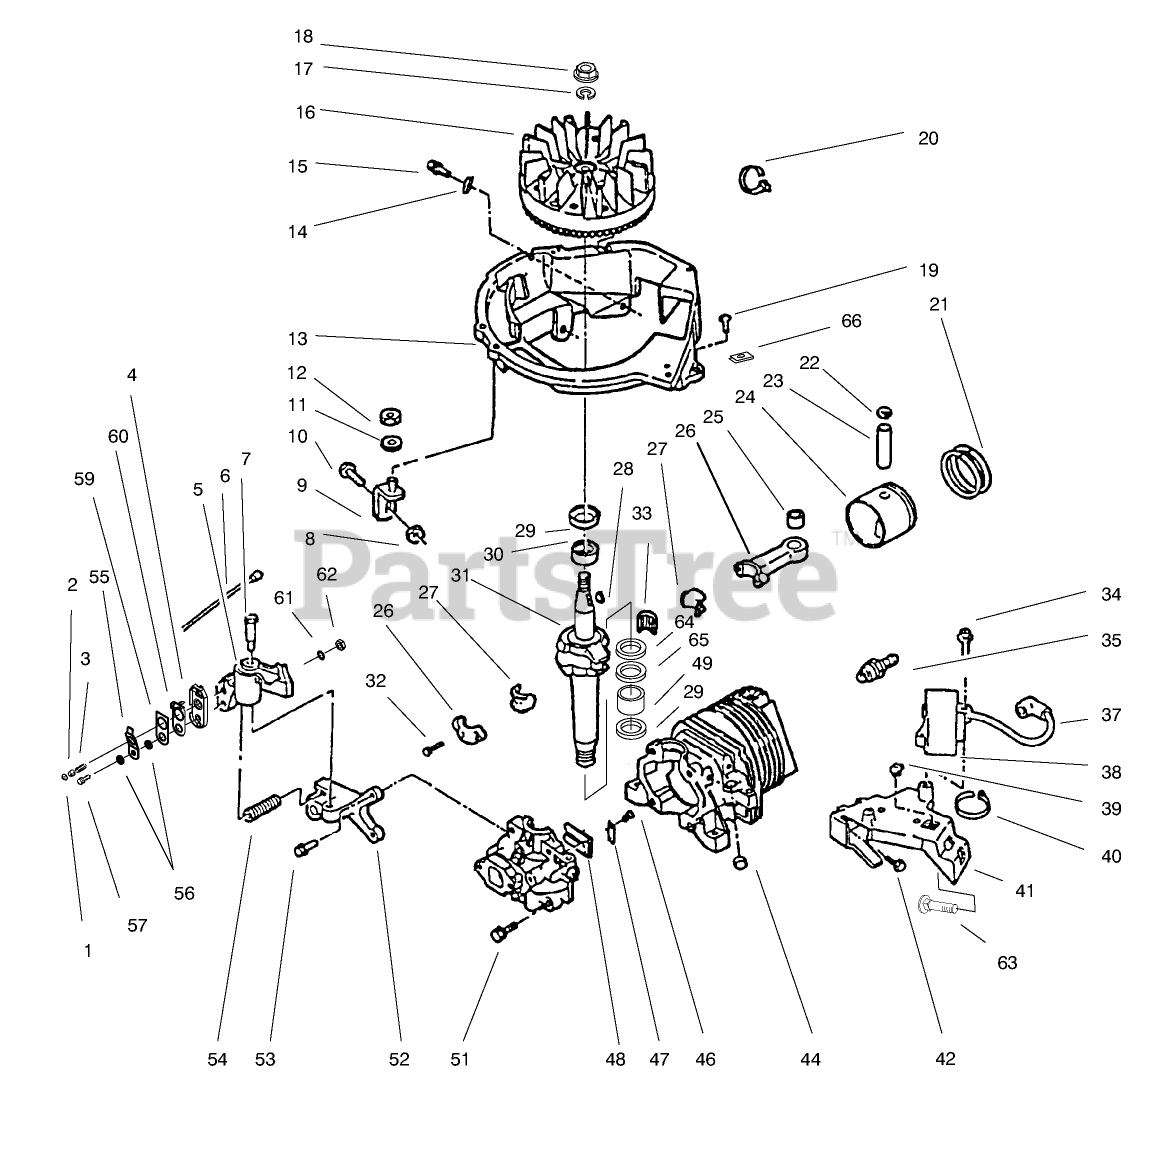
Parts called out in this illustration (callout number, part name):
1	RETAINER S
2	ACTUATOR-LEVER, BRAKE
3	SPRING
4	CASE - SWITCH EF
5	BRAKE AY FE
6	WIRE LEAD AY F
7	SCREW-SHOULDER
8	NUT-LOCK F
9	BRACE AY F
10	BOLT F
11	WASHER
12	LOCKNUT E
13	BASE SHROUD F
14	"J" CLIP F
15	SCREW F
16	FLYWHEEL ASSY F
17	WASHER-LOCK
19	SCREW F
20	STRAP-TIE
21	F-RING SET
22	RING-RETAINING
23	PIN-WRIST VF
24	Set-Piston & Ring (Incl. Ref.# 21-23)
25	BEARING XEV
26	Assembly-Conn. Rod (Incl. Ref. #25, 27, 32, & 33)
27	LINER ASM
29	SEAL-OIL
30	BEARING V
31	CRANKSHAFT V
32	SCREW-HSH
33	Roller Strip
34	SCREW F
35	SPARK PLUG
37	HT LEAD&COVER XEV
38	C. D. Ignition Module (Incl. Ref. #37)
39	NUT-CLIP
40	TIE-CABLE
41	BRACKET F
42	SCREW F
44	PLUG-CORE VF
46	SCREW-HH
47	PLATE-BACKUP, REED
48	REED-CARBURETOR
49	BEARING V
51	SCREW-H.W.HD. F
52	BRACKET-BRAKE F
53	SCREW
54	SPRING-BRAKE
55	SPRING-CONTACT
56	WASHER
57	SCREW-HH
59	SHIELD
60	PLATE-CONTACT
61	WASHER-LOCK/EXT
62	Nut
63	SCREW-CARRIAGE
64	BEARING-THRUST
65	WASHER-THRUST
66	NUT-SPEED
